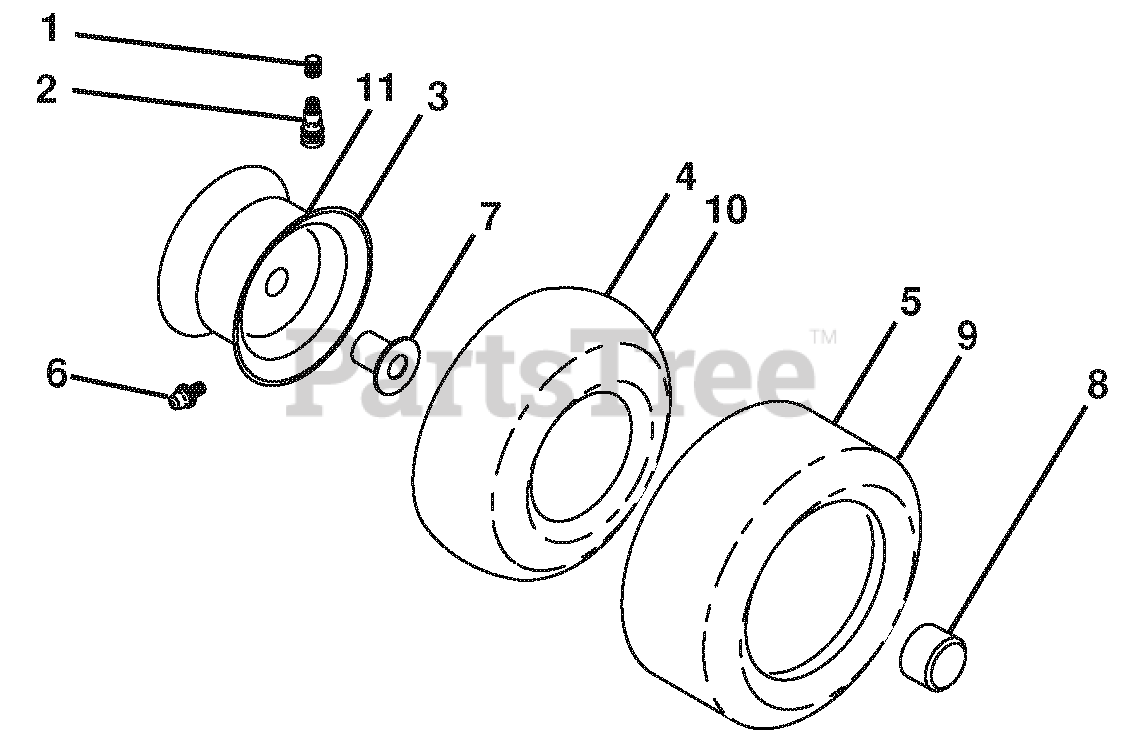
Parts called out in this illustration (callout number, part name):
1	CAP.VALVE.TIRE
2	STEM.VALVE
3	RIM ASM FRONT
4	TUBE.INNER.FRONT.#35060
5	TIRE.F.TS.15 X 6.0 - 6.SERVICE
6	FITTING, GREASE
7	BEARING FLANGE
8	CAP AXLE
9	TIRE.R.TS.20 X 8-8.C.SERVICE
10	TUBE, REAR
11	RIM ASM REAR
